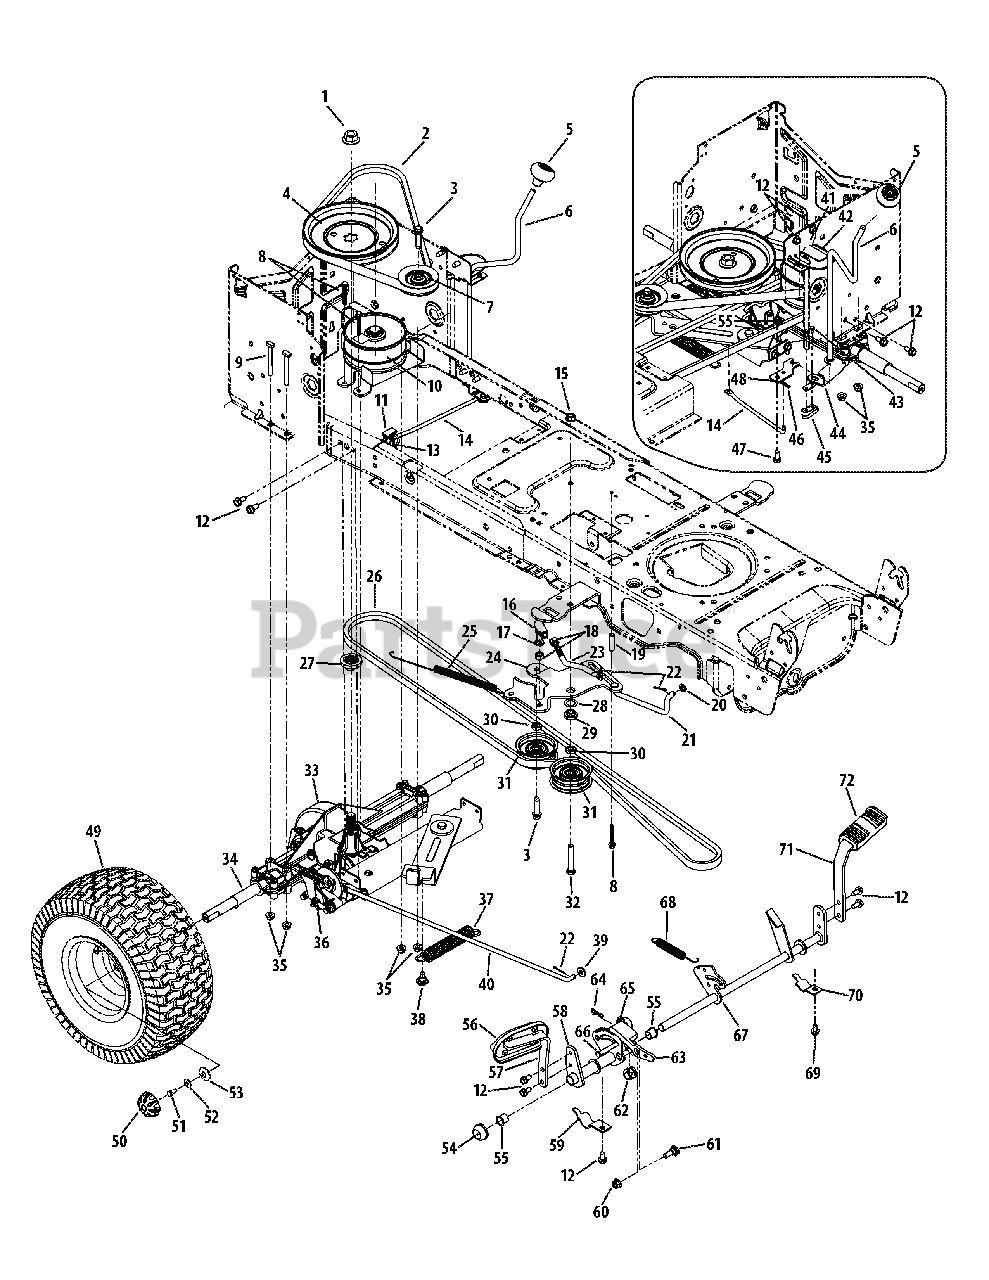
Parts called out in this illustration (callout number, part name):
1	Flange Nut
2	V-Belt
3	Hex Washer Screw, 3/8-16 x 1.500
5	Shift Knob
6	Shift Lever Assembly
7	Idler Pulley
8	Hex Washer Screw, 1/4-20 x 1.750
9	Bolt, 5/16-18 x 2.75
10	Variable Speed Pulley Assembly
11	Shift Plate Bearing
12	Hex Washer Screw, 5/16-18 x .750
13	Internal Cotter Pin
14	Shift Rod
15	Flange Lock Nut, 3/8-16
16	Joint Ball
17	Lock Washer, 3/8
18	Hex Nut, 3/8-24
19	Spacer, .260 x .372 x 1.420
20	Flat Washer, .385 x .62 x .063
21	Foot Pedal Transmission Bypass Rod
22	Cotter Pin, 3/32 x 1.0
23	Idler Adjuster Rod
24	Idler Bracket
25	Extension Spring, .70 x 12.00
26	V-Belt
27	Pulley Hub
28	Shim Washer, 1.00 x .632 x .010
29	Shoulder Spacer, 1.00 x .38 x .38
30	Jam Nut, 7/16-20
31	Flat Idler Pulley
32	Hex Screw, 3/8-16 x 2.25
33	Transmission Drive Assembly
34	Sleeve, .758 x .821 x 2.4375
35	Flange Lock Nut, 5/16-18
36	Extension Spring, .59 x 4.00
37	Extension Spring, .97 x 6.18
38	Shoulder Screw, 5.16-18 x .43 x .29
39	Flat Washer, .344 x .750 x .120
41	Shift Bracket
42	Spring Shifter Clip
43	Hex Washer Screw, #8-18 x .500
44	Insulator Nut Plate
45	Short Spring Switch
46	Cotter Pin, .072 x 1.13
47	Hex Screw, 5.16-18 x .625
48	Shift Adjustment Bracket
49	Wheel, Complete, 20 x 8 x 8
49	Rim Assembly, 8.0 x 7.0 x.750
49	Tubeless Air Valve
49	Tire, 20 x 8 x 8
50	Hub Cap
51	Hex Lock Screw, 5.16-24 x .750
52	Bell Washer, .340 x .872 x .060
53	Flat Washer, .350 x 1.59 x .062
54	Push Cap, 5.8
55	Flange Bearing, .630 x .695 x .60
56	Control Pad
57	Auto Drive Control Pedal Assembly
58	Transmatic Pedal Bracket Assembly
59	Pedal Strap Support Bracket
60	Flange Lock Nut, 3.8-16
61	Shoulder Bolt, 3.8-16 x .500 x .270
62	Hex Flange Bearing
63	Cruise Latch
64	Bow-Tie Cotter Pin
65	Bracket Reinforcement Plate
66	Clevis Pin, 5.16-3.985
67	Brake Control Assembly
68	Extension Spring, .63 x 4.95
69	Hex Washer Screw, 5.16-18 x .625
70	Pedal Strap Support Bracket
71	Brake Pedal Bracket
72	Brake Pedal Pad
